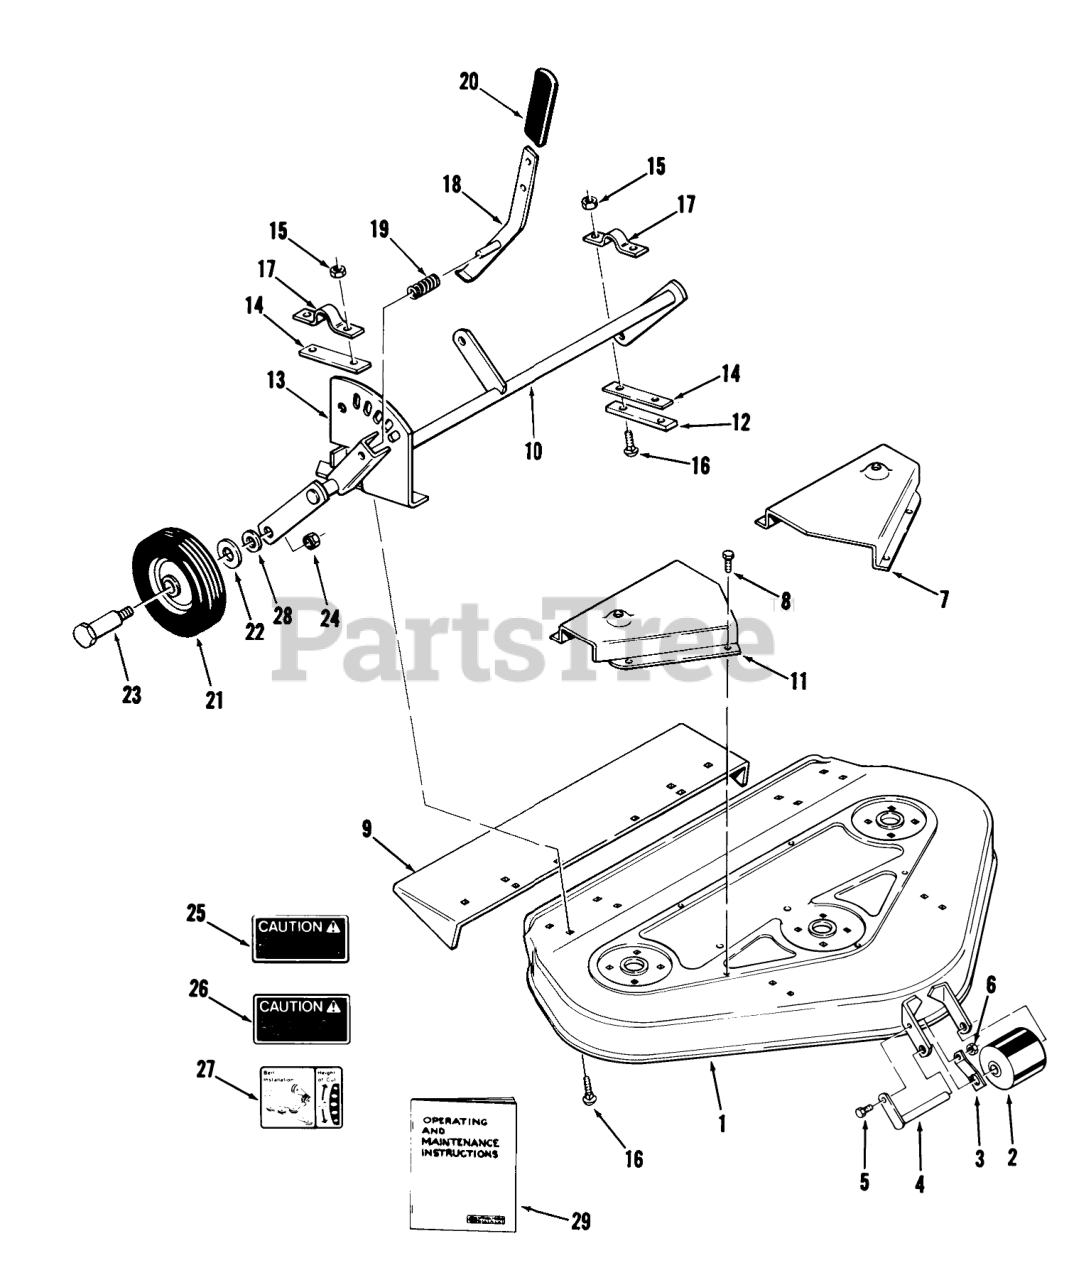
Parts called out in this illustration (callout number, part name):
1	Mower Deck
1	ASSY-MOWER DECK 3 R
2	Roller
3	SPRING ROLLER STOP
4	Roller Shaft
5	H H C S
6	Nut
7	Cover-Belt
8	Bolt
9	Chute Extension
10	Gage Wheel Support
11	Belt Cover RH
12	Strap
13	Quadrant
14	Strap 1/16
15	Nut
16	Bolt
17	CLAMP
18	Lever
19	SPRING-COMPRESSION
21	Wheel 6 x 1.75
22	WASHER
23	BOLT-SHOULDER
24	Nut
25	Caution Decal
26	Decal-Caution
27	DECAL-HEIGHT & BELT
28	WASHER
29	Operating and Maintenance Instructions
